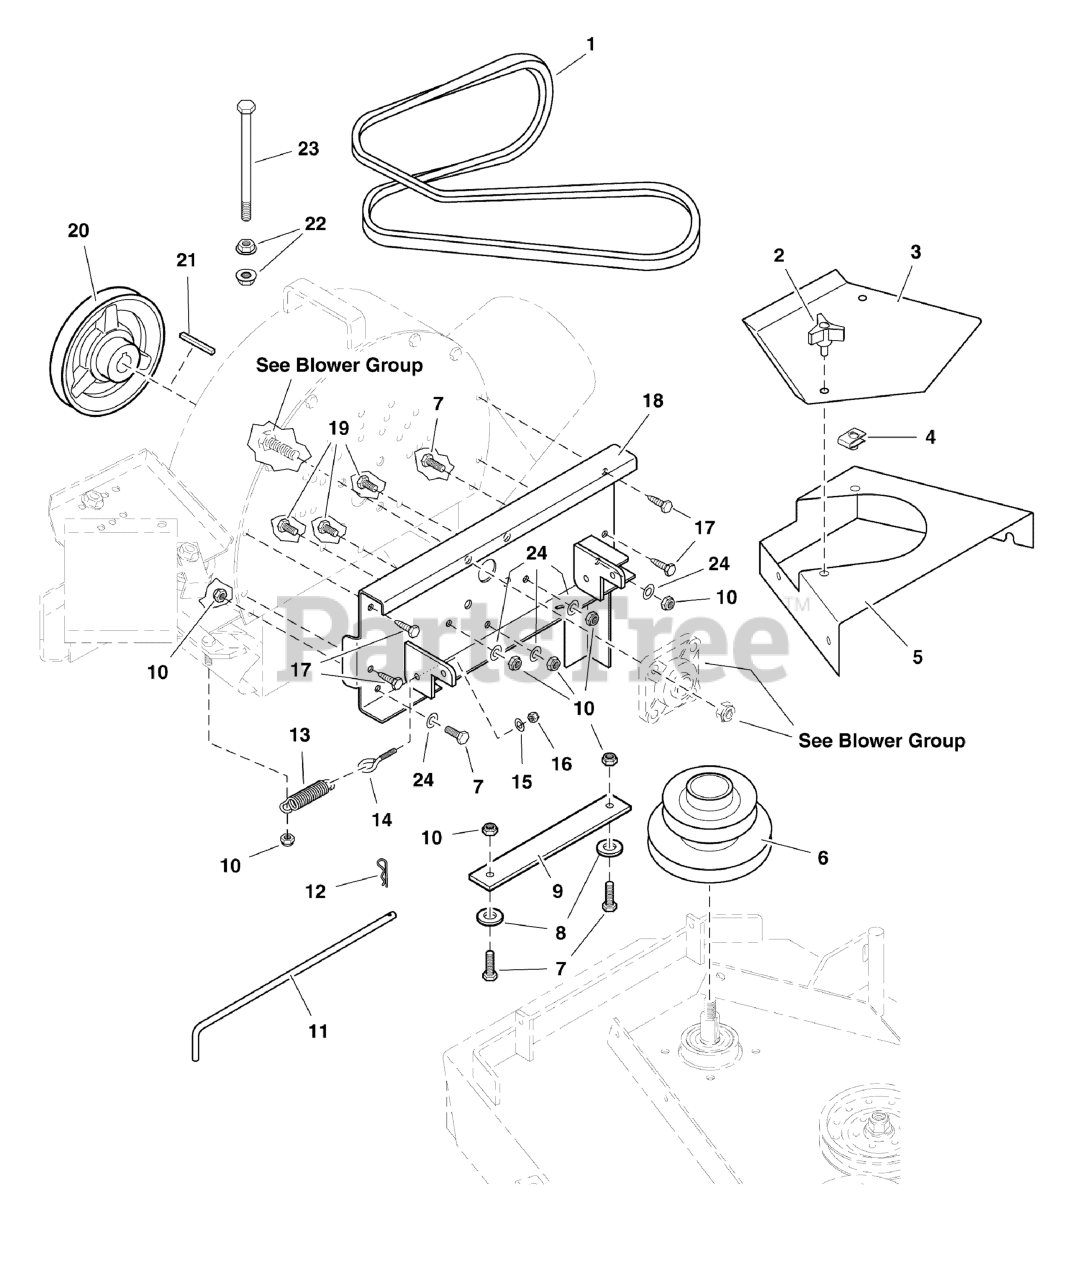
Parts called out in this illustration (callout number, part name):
1	BELT, A-SEC, 92.00EL, ARAMID, WRPD
1	BELT
2	KNOB
3	BELT SHIELD
4	BODY CLIP, 5/16-18-7GA MATERIAL
5	DECK GUARD
6	SPINDLE PULLEY, 48"
6	SPINDLE PULLEY, 52"
7	BOLT, 5/16-18 X 1 GD5 YZ
8	WASHER, 5/16 x 1
9	QUICK CONNECT BAR
10	NUT, 5/16-18 Hex Nylon Lock
11	QUICK CONNECT ROD
12	HAIRPIN CLIP
13	SPRING, Extension
14	EYE BOLT, 1/4-20 X 2.5, 1THRD, .5EYE,CZ
15	WASHER, 1/4 SAE
16	NUT, 1/4-20 HEX NYLON LOCK
17	BOLT, Self-Tapping, 5/16-18 x 3/4
18	48" BLOWER MOUNT
18	52" BLOWER MOUNT
19	BOLT, 5/16-18 X 3/4 GD5
20	48" BLOWER DRIVE PULLEY
20	PULLEY, BLOWER AXLE, 52
21	KEY, 1/4 SQ. X 1-1/2
22	NUT, 3/8-16 Hex Serrated Flange
23	BOLT, 3/8-16 X 6" GD5 CZ
24	WASHER, 5/16" SAE
